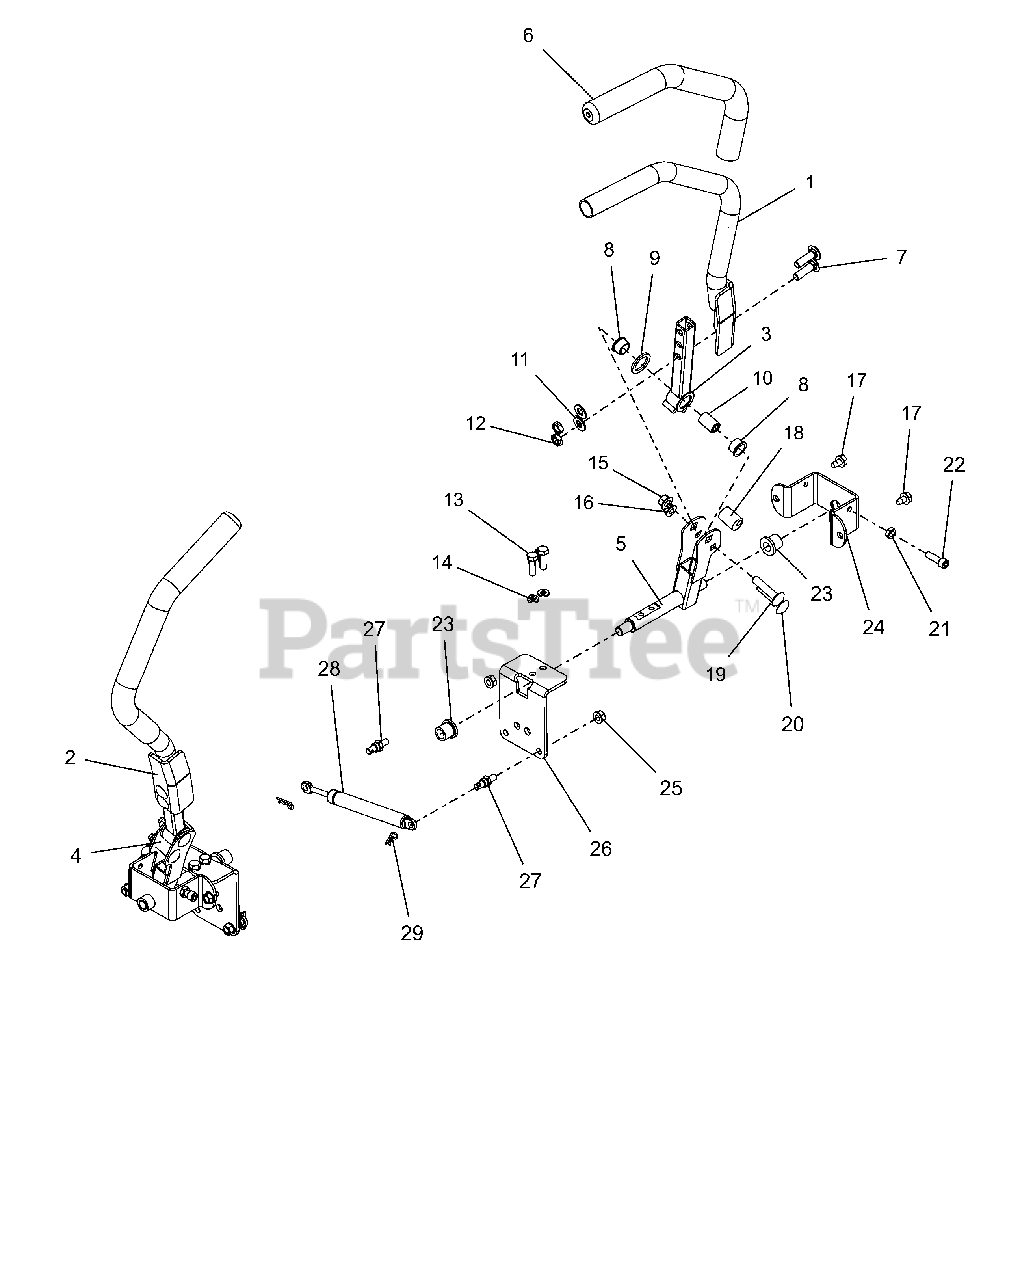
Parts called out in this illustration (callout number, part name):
1	WLDMT, STEERING HANDLE LH
2	WLDMT, STEERING HANDLE RH
3	WLDMT, UPPER CONTROL ARM
4	WLDMT,STEERING ARM LOWER RIGHT
5	WLDMT,STEERING ARM LOWER LEFT
6	GRIP, HANDLEBAR 15" FOAM
7	BLT,RHSSN-.375X1.25 G5 RIE5230
8	BSHG-FLG, .625X.75X.450X.875
9	WASHER, FRICTION .875X1.25X.10
10	SPACER, .375X.625X.970 (PM)
11	WSHR,FLT .406X.812X.065 ZCC
12	@NUT-LK-CTR-JAM .375-16 YWZC
13	BLT, HEX .31-18X1.00 G8 ZCC
14	WSHR,LK-REG .312X.078 ZCC
15	NUT-LK-CTR-FLG .375-16 GF ZCC
16	NUT,NYL-FLG .31-18 GF ZCC
17	SCR,TAP .312-18X.50 HWH TR ZCC
18	BSHG,ECCEN .328X.750X1.01 PM
19	BLT,RHSSN-.375X1.75 G5 RIE5230
20	BLT,RHSSN-.312X1.75 G5 RIE5230
21	NUT-JAM .312-18 G2 ZCC
22	SCR, SKH .312-18X1.00 G8 ZC120
23	BSHG-FLG .515X.750X.745X1.00NY
24	BRKT, STEERING
25	NUT-LK-TOP-FLG .312-18 GF ZCC
26	BRKT, STEEERING
27	COUPLER, DAMPER MOUNT
28	DAMPER, STRAIGHT MOUNT
29	PIN, HAIR #213 .08X1.19 ZCC
